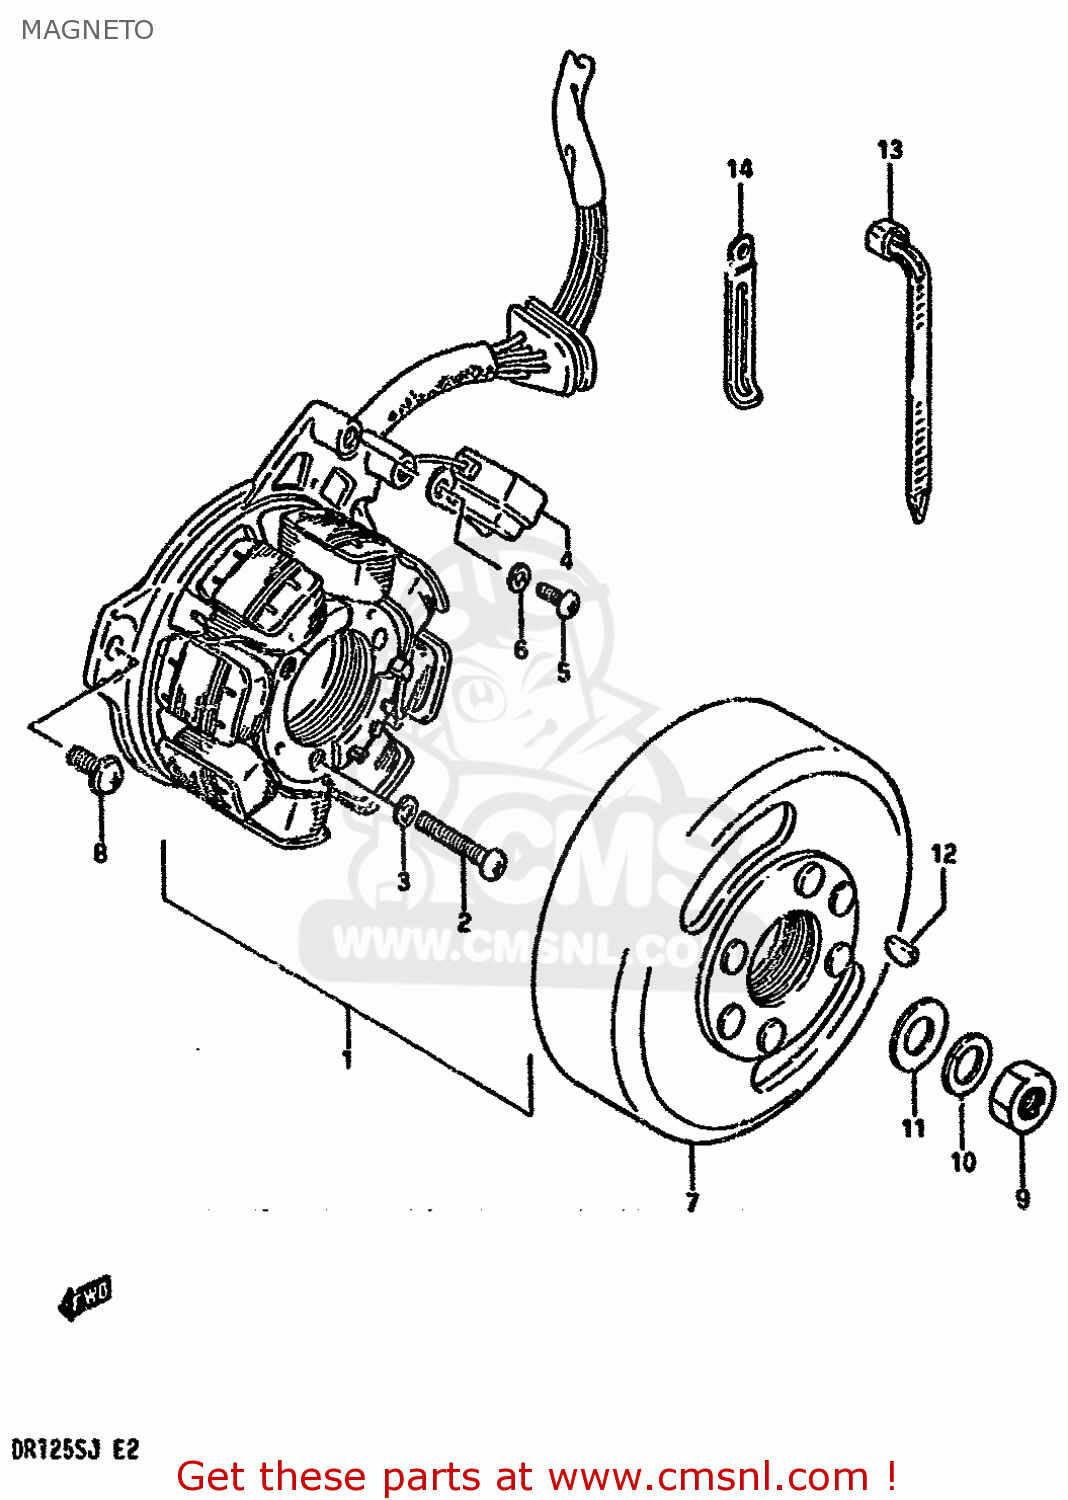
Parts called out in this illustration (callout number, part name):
1	STATOR ASSEMBLY
2	SCREW
3	LOCK WASHER
4	COIL,PICK UP
5	SCREW
6	LOCK WASHER
7	ROTOR
8	SCREW(5X14)
9	NUT (10MM)
10	WASHER,LOCK,10
11	WASHER
12	KEY
13	CLAMP(L:125)
14	CLAMP
